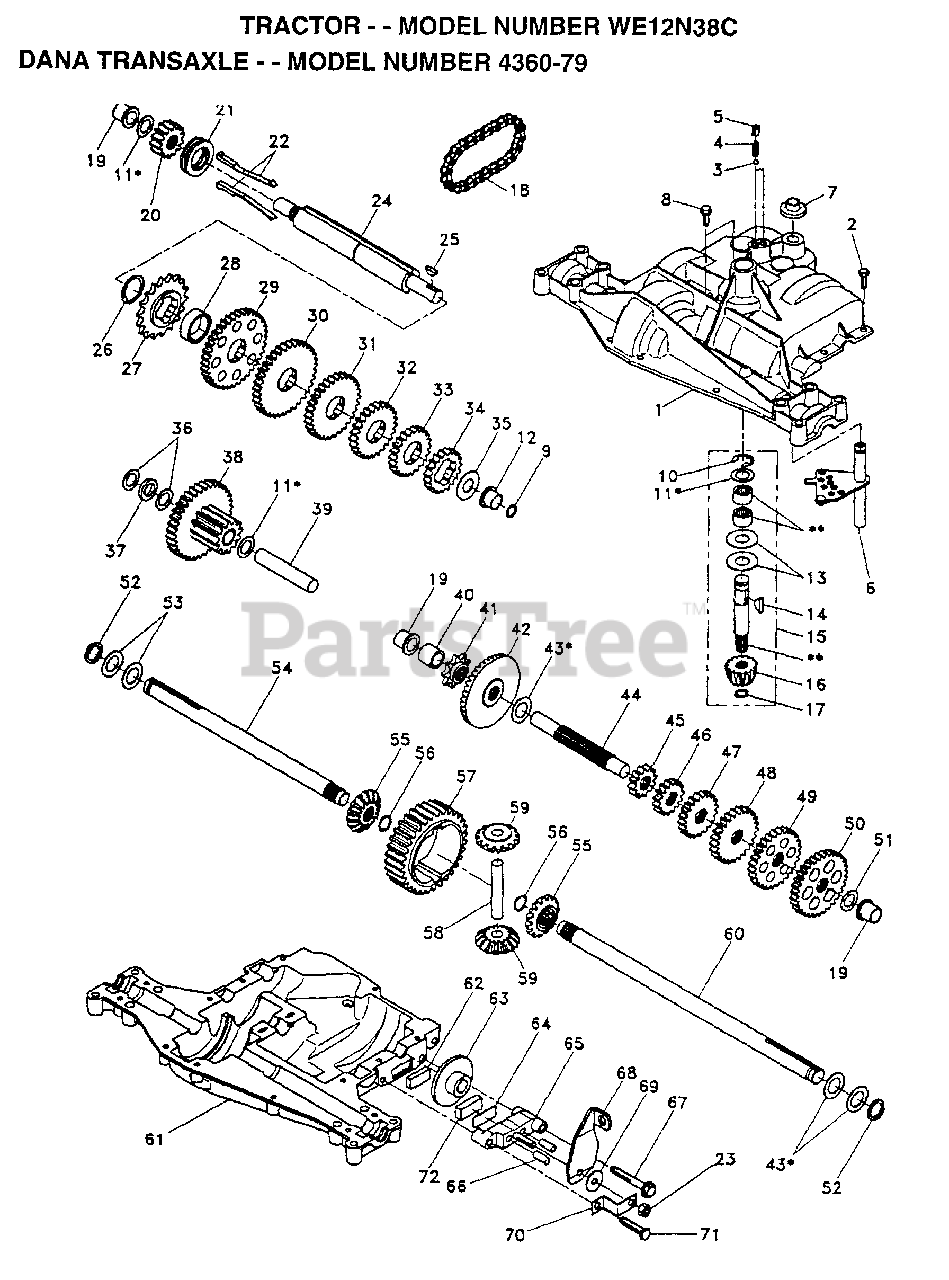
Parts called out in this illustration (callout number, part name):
1	HOUSING UPPER TRN
4	"SPRING, DETENT LT"
5	"SCREW, SET LT"
6	KIT SHIFTER ASM
7	SHIFTER BOOT
8	SCREW TAP W/SEAL
9	SQUARE RING
11	ASM KIT SHIM 4689
12	BEARING FLAN-DANA
13	WASHER T
14	KEY WOODRUFF-DANA
15	AS KIT INPUT SHFT
16	PINION 14T T
17	"RING,RETAINING LT"
18	"CHAIN,24 PTCH LT"
19	BEARING.FLNG.5510
20	GEAR SPUR 14 TTH
21	COLLAR CLUTCH
22	ASM KIT CLTCH KEY
23	NUT.LOCK.5/16-24
24	SHAFT INTERM DANA
25	WOODRUFF KEY
26	"RING,RETAINING LT"
27	SPROCKET 18T T
28	SPACER YT
29	GEAR SPUR 37 TTH
30	GEAR SPUR 35 TTH
32	GEAR 25T LT
33	GEAR SPUR 22 TT
34	SPUR GEAR 19T
35	"WASHER, PLAIN LT"
36	WASHER 025
37	SPACER
38	ASSM GEAR COMB
39	SHAFT IDLER
40	SPACER T
41	SPROCKET 9T LT
43	ASM KIT SHIM
44	SHAFT T
45	GEAR SPUR 12 TTH
46	GEAR SPUR 15 TTH
48	"GEAR, SPUR 25T LT"
49	GEAR 28T T
50	"GEAR, SPUR 31T LT"
51	WASHER 060
52	NEOPRENE WASHER
53	WASHER 031
55	GEAR 15T T
56	"RING,RETAINING LT"
58	SHAFT T
59	GEAR 1ST T
61	HOUSING LOWER TNS
62	PUCK T
63	BRAKE DISC. T
64	SPACER LT
66	PIN T
69	WASHER LT
71	"SCREW, TAPPING LT"
72	PUCK T
